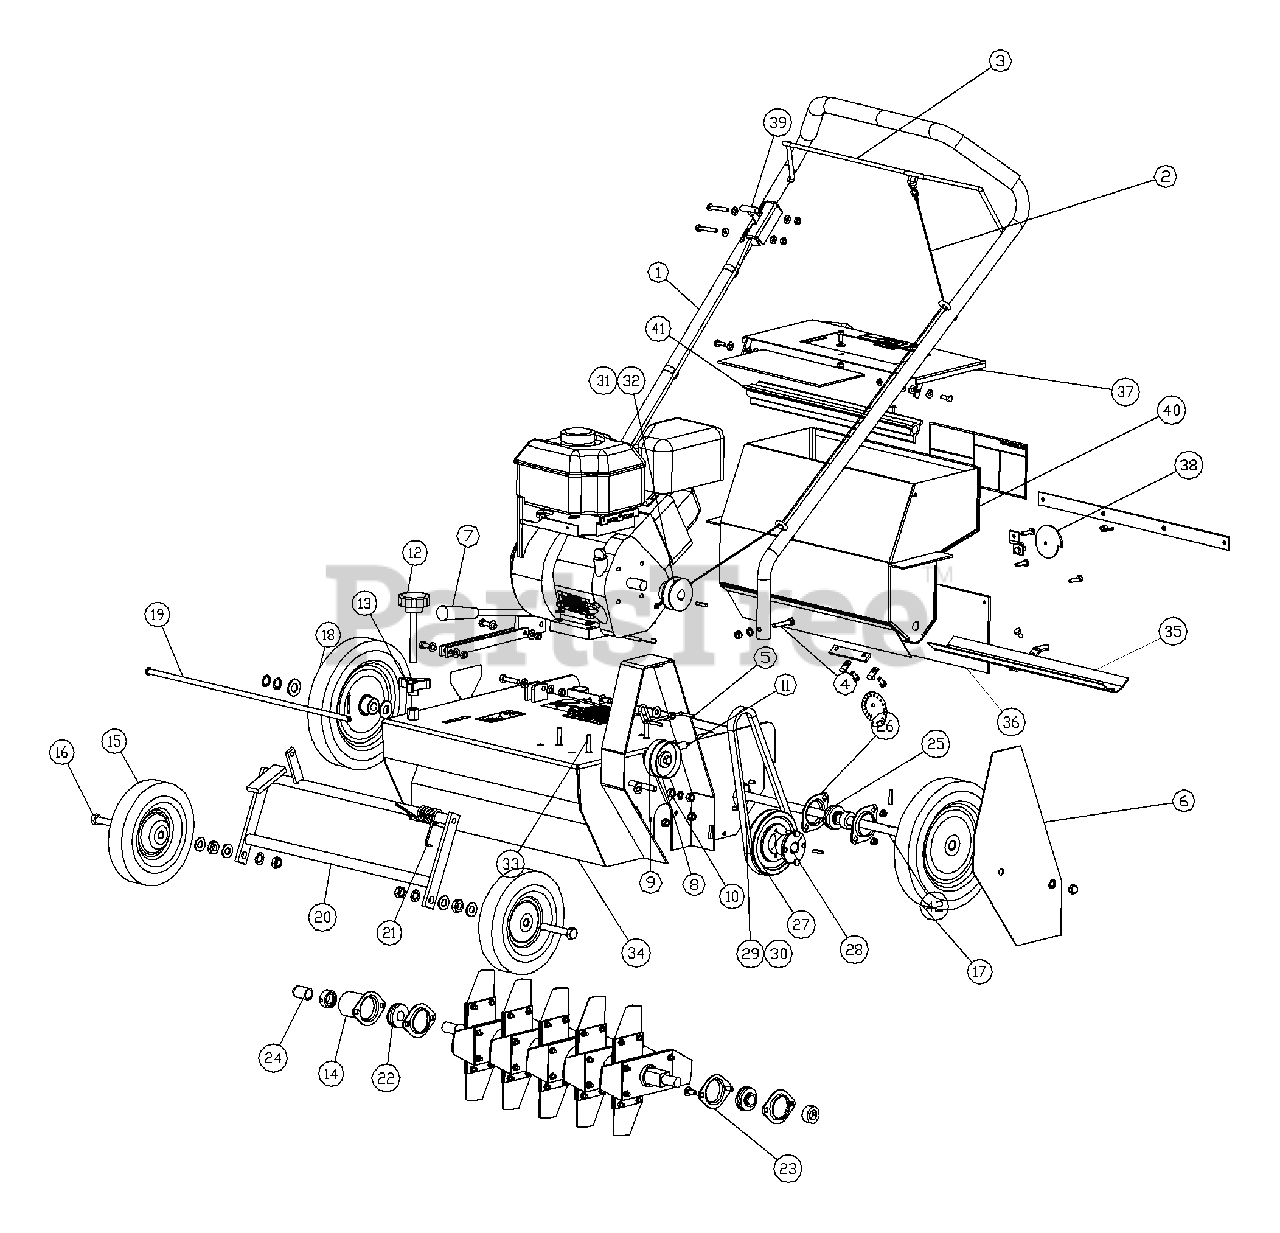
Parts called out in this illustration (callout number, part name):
1	Handle Assembly.
2	Clutch Cable Assembly.
4	Bolt kit, handle
5	Belt keeper kit
6	Belt Guard Kit
7	Depth Lever Assembly.
8	Idler Assembly Kit
9	Pulley, idler 2 3/4 OD
10	Mounting Arm, idler pulley
11	Spring, idler return
12	Depth Adjustment Knob
13	3 - pronged lock depth knob
14	Rotor guard
15	Front Wheel, 8 x 1 3/4, ball bearing
16	Bolt kit for front wheel
17	Wheel , left rear kit
18	Wheel, right rear kit
19	Lift Arm Rod Kit
20	Lift Arm Assembly Kit
21	Torsion spring
22	Bearing, 3/4 with locking collar
23	Stamping Kit
24	Rotor cap, 3/4 ID
25	Bearing, 5/8 with locking collar
26	Stamping kit
27	V - Pulley, B-5.0 OD, tapered bore
28	Bushing kit
29	V-Belt, B-34 special
30	V-Belt, B-36 special
31	V - Pulley engine kit for 3/4 bore
32	V - Pulley engine kit for 1" bore
33	Engine Bolt Kit
34	Deck, DT18
35	Deflector kit
36	Deflector, neoprene
37	Lid, seed hopper kit
38	Dial, gage kit
39	Control, push/pull kit
40	Seed hopper
41	Agitator bar
42	Axle, 5/8 shaft, seeder
